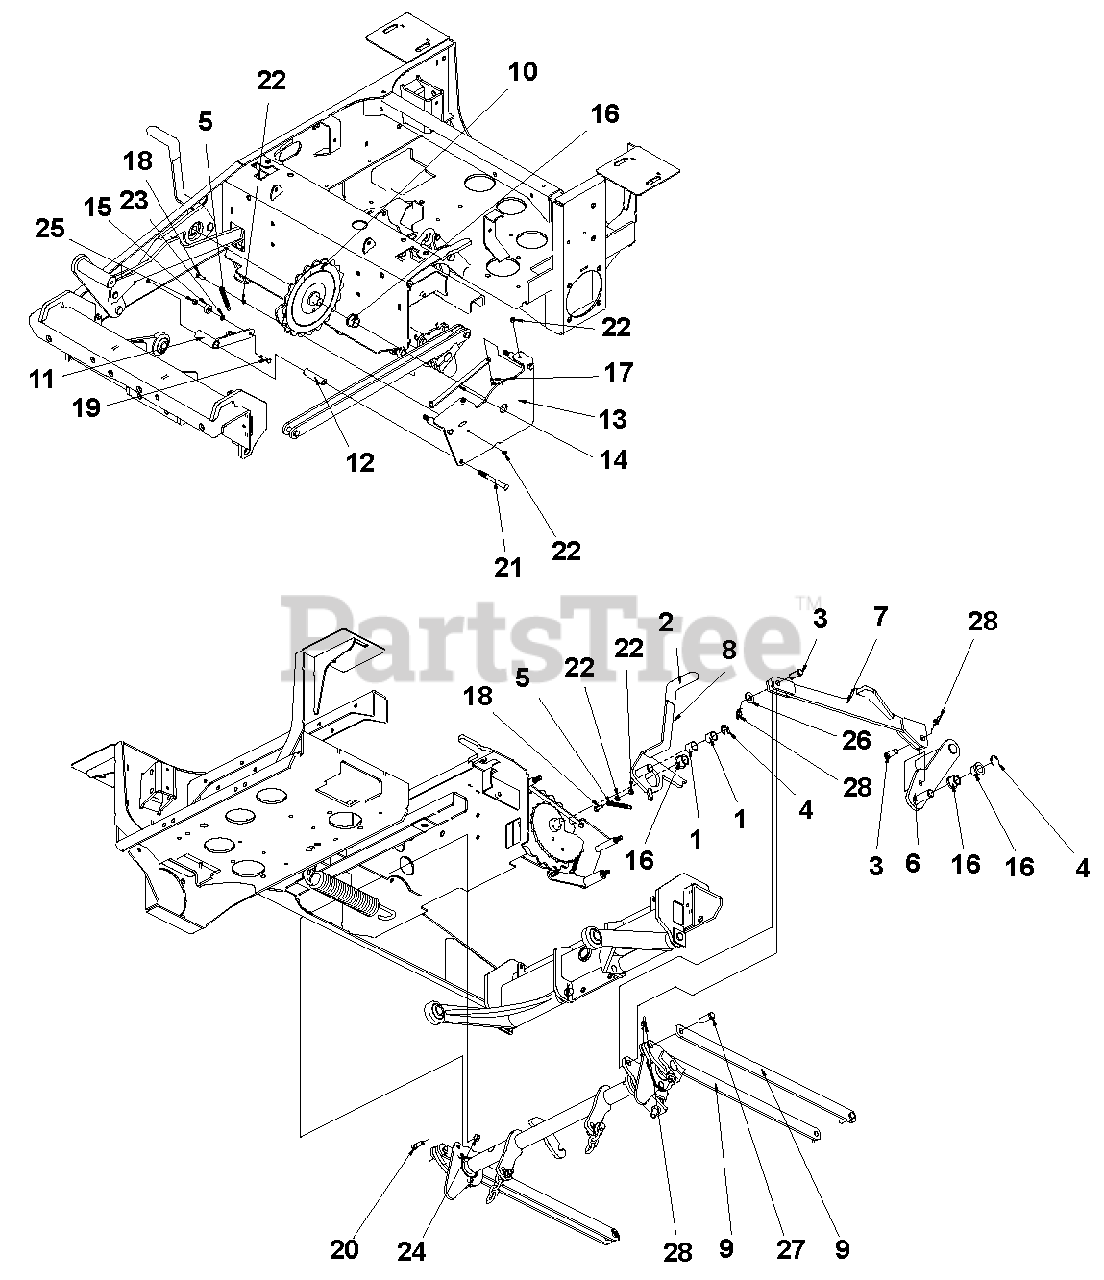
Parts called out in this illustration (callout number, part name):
1	Bearing, Sleeve .753 x .878 x .750
2	Grip, Rubber Lever
3	Pin, Clevis .500 x 1.25 x 1.02 Y
4	E-Ring, .750 x .050
5	Spring, EXT .375 x .055 x 2.25
6	Weldment, Foot Arm
7	Weldment, Foot Connector
8	Weldment, Transportation Lock
9	Plate, Connector Link
10	Weldment, Cam Control w/Decal
11	Weldment, Arm
12	Spacer, Ø.625 x Ø.385 x 2.53 HOC
13	Plate, HOC Indicator
14	Plate, Finger Guard
15	Bearing, Ball .250 x .688 x 313
16	Bushing, .750 x 1.00 x .750
17	Bolt, 1/4-20 x .500 HEX 5
18	Bolt, 1/4-20 x .750 HEX 5
19	Bolt, 1/4-20 x 1.00 HEX 5
20	Bolt, 1/4-20 x 1.00 HEX 5
21	Bolt, 3/8-16 x 3.50 HEX 5
22	Nut, 1/4-20 STD HEX GR5
23	Washer, M6 REG Flat
24	Locknut, 3/8-16 Crow
25	Locknut, 1/4-20 Nyloc
26	Washer, .500 x 1.00 x .105 FLAT
27	Pin, Clevis .500 x 1.50 x 1.27
28	Ring, Rue .500 x .062 x 1.420
